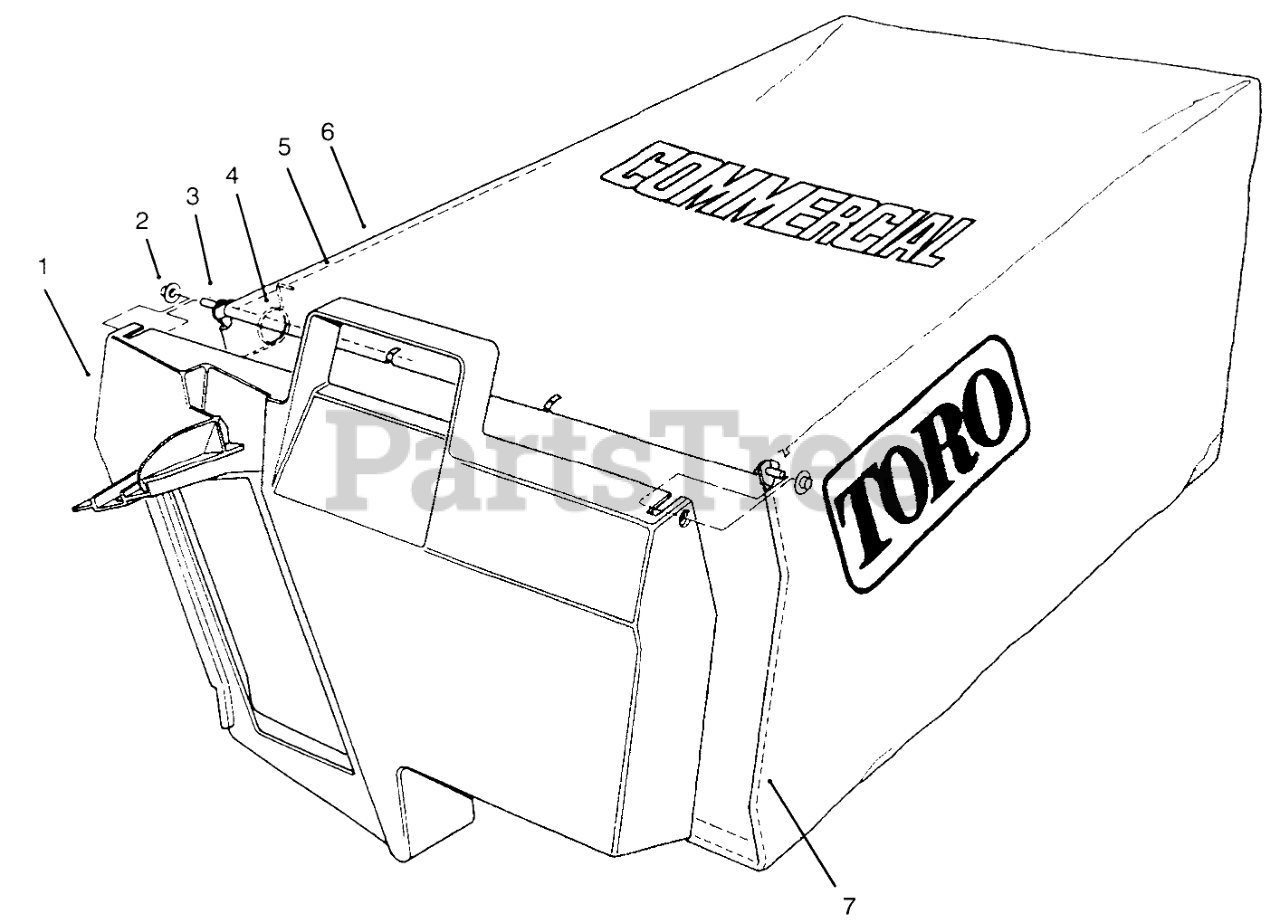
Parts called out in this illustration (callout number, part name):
1	DOOR-BAG, GRASS
2	NUT-PUSH
3	HINGE-DOOR, BAG
4	SPRING
5	FRAME-BAG, UPPER
6	Bag
7	FRAME-BAG
